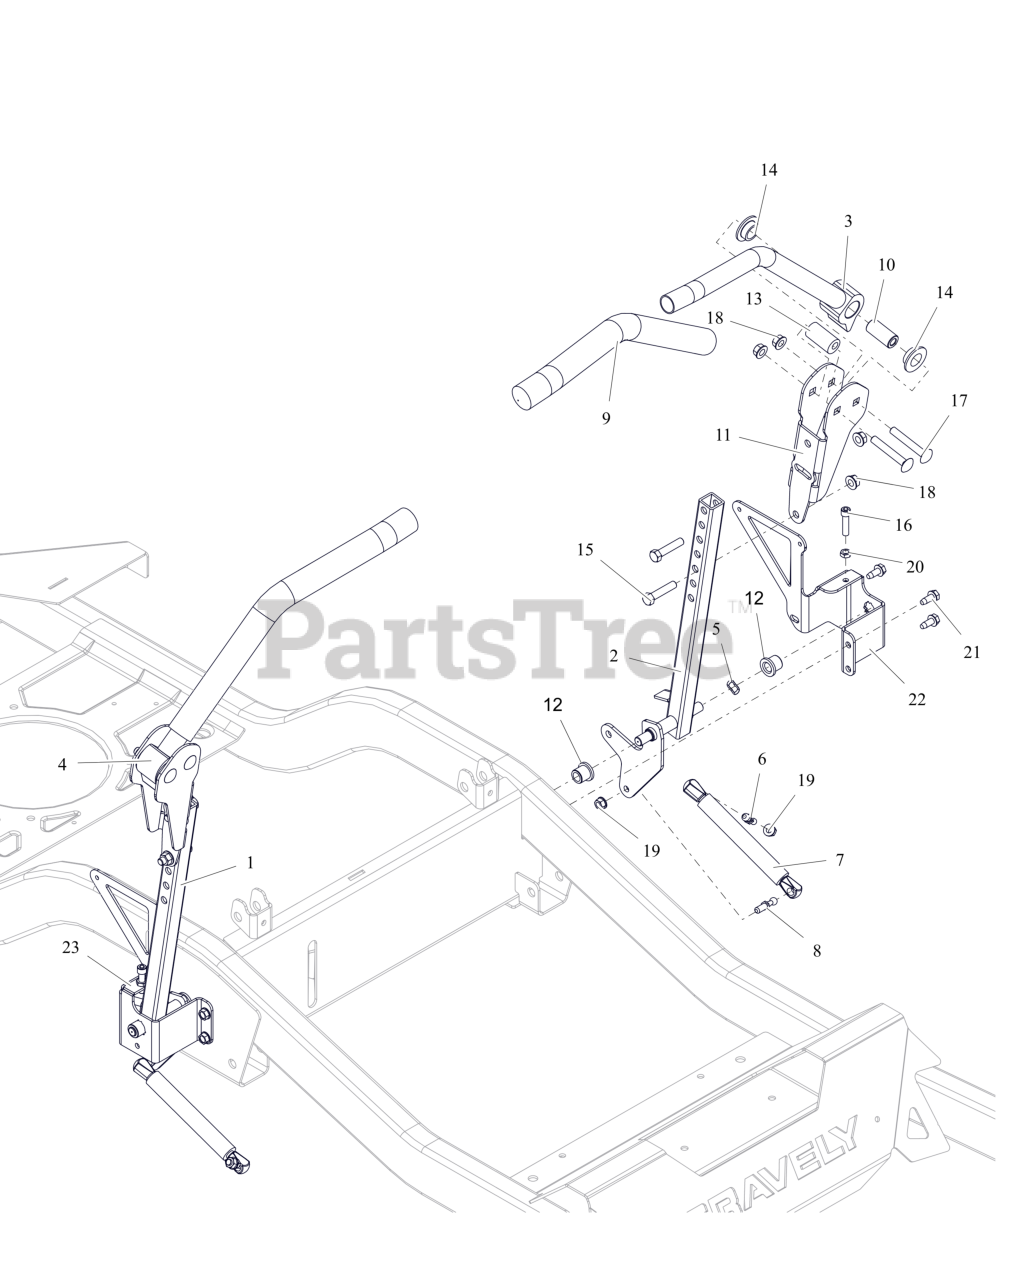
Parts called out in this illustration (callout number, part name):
1	WLDMT, STEERING RH (RED)
2	WLDMT, STEERING -LH (RED)
3	WLDMT, CONTROL HANDLE-LH (RED)
4	WLDMT, CONTROL HANDLE-RH (RED)
5	WAVE WASHER .531X.781X.125FH
6	STUD- BALL
7	DAMPER
8	STUD-BALL-THREADED
9	GRIP, HANDLEBAR
10	SPACER, STEERING ARM
11	BRKT, ADJ UPPER CONTROL ARM (RED)
12	BHSG-FLG .500X.750X.750X.125
13	BSHG, ECCENTRIC.406X.875X1.625
14	BSHG-FLG .762X1.48X.44 NYL
15	BLT, HEX .38-16X1.75 G5 ZCC
16	SCR, SKH .312-18X1.25 GR8 ZC120
17	BLT, RHSSN.38-16X2.50 G5 ZCC
18	NUT-LK-TOP-FLG .38-16 ZC120
19	NUT,LK-CTR-FLG .31-18 GF ZCC
20	NUT-JAM .312-18 G2 ZCC
21	SCR,TAP .312-18X.75 HWH TR ZCC
22	BRKT, STEERING ARM MOUNTING -LH (RED)
23	BRKT, STEERING ARM MOUNTING- RH (RED)
